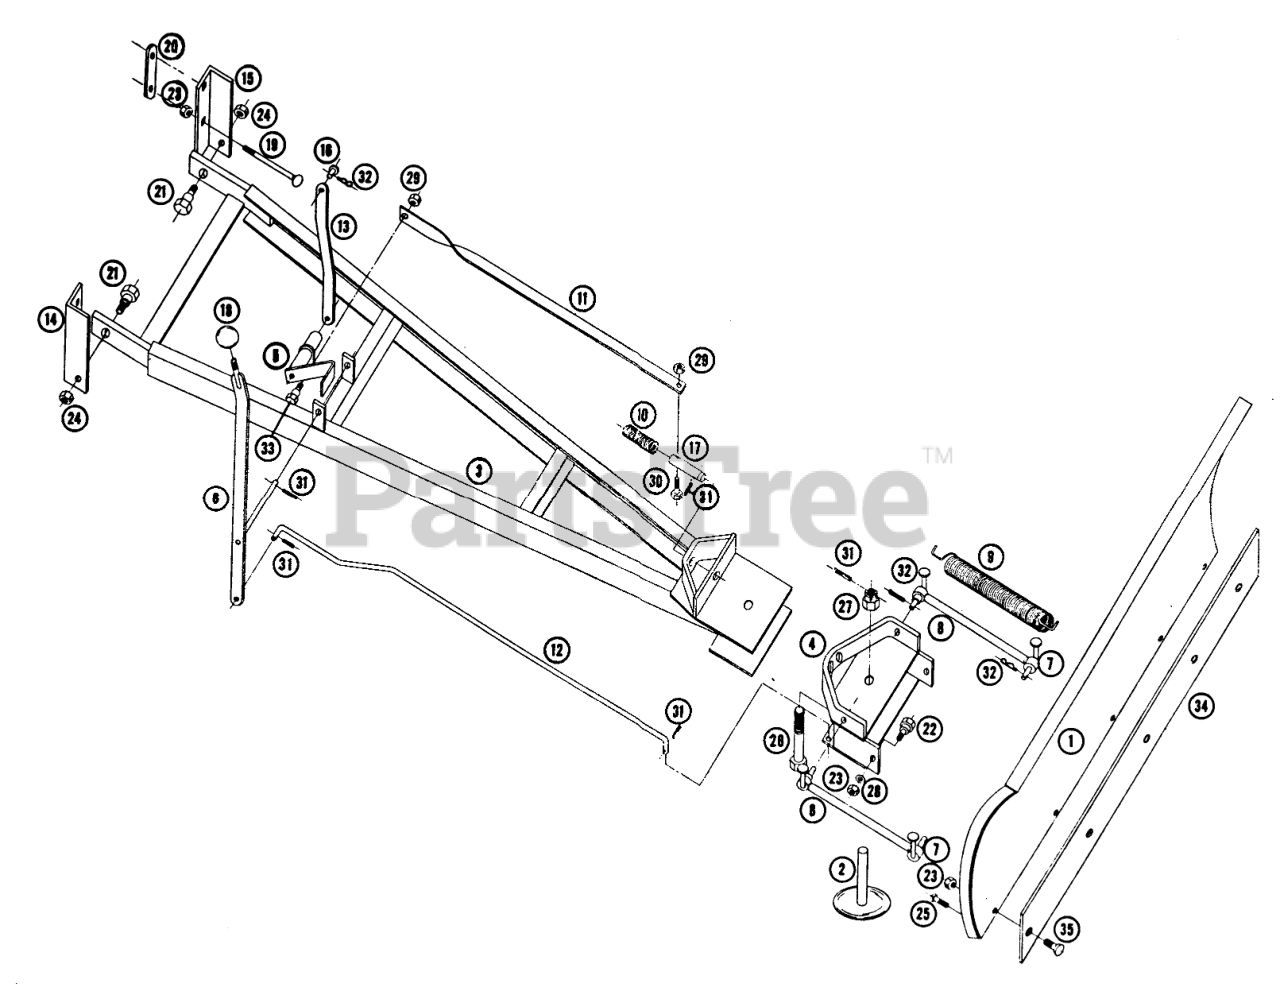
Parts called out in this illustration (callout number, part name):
1	Blade Assy. W/A
2	Skid
3	Frame W/A
4	Nut-Flywheel
5	Foot Lever Ass-y.
6	Ass-y. Lever W/A
7	Inside Spring Retainer W/A
8	Spring Hook Assy. W/A
9	Tension Spring
10	SPRING-COMPRESSION
11	Bar-Trip
12	Pivot Rod
13	Lift Bar
14	Bracket-R.H. Mtg.
15	Bracket-L.H. Mtg.
16	Pin-Lift Lever
17	Index Pin
18	Knob
19	Carriage Bolt
20	Link-Mtg. Bracket
21	Bolt Shoulder
22	Bolt-Shoulder
23	Nut
24	Nylock Nut 1/2-13
25	Sq. Hd. Set Screw
26	Bolt-Hex 3/4-16 x 3 3/4
27	Hex Hd. Castle Nut 3/4-16
28	Washer, 3/8
29	1/4-20 Lock Nut
30	Hex Hd. Cap Screw
31	Cotter Key
32	Hair Pin Cotter
33	Bolt-Shoulder
34	Plate
35	Carriage Bolt, 3/8 x 3/4
